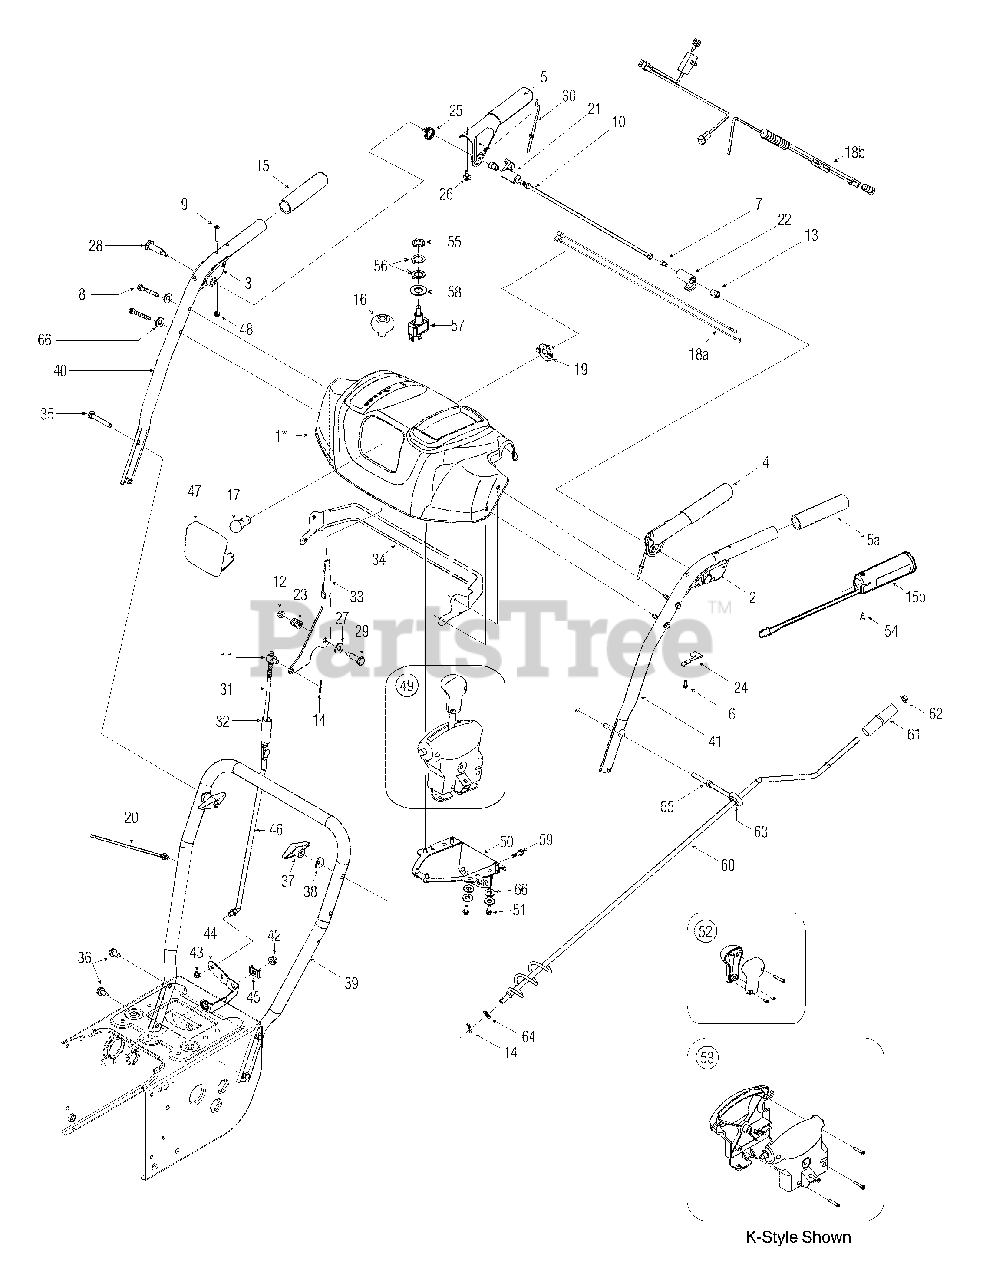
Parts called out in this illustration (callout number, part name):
1	Panel Ass'y, Handle, Black, H-Style
2	Handle Assembly, Clutch Lock, LH
3	Handle Assembly, Clutch Lock, RH
4	Handle Assembly, Engagement, LH
5	Handle Assembly, Engagement, RH
6	Screw, #8-16 x.50
7	Screw, 1/4-20 x.375
8	Screw, Self-tapping, 1/4-20 x 1.750
9	Screw, Machine, #10-24 x 1.375
10	Rod, Pivot
11	Ferrule, 5/16-18 x.312
12	Nut, Flange Lock, Nylon, 1/4-20
13	Nut, Shoulder, Hex, 1/4-20,
14	Pin, Cotter,.072 Dia. x 1.13
15A	Grip, 1.0 ID x 5.0
15B	Heated Grip
16	Knob, Shift
17	Lamp
18A	Harness, w/o Heated Grips
18B	Harness, Heated Grips
19	Socket, Lamp
20	Tie, Cable, 19 x 8.39", Tree Mount
21	Plate, Lock
22	Cam, Clutch Lock
23	Spring, Compression,.39 x.60 x.88
24	Spring, Clutch, Lock
25	Spring, Torsion, 0.8156 ID x.3038
26	Bumper, Rubber,.62 OD x.22
27	Washer, Flat,.385 x.870 x.092
28	Screw, Shoulder,.437 x 1.345, 1/4-20
29	Screw, Shoulder,.374 Dia. x 1.05
30	Z-Fitting, Cable
31	Rod, Shift,.312 x 9.0 Upper
32	Connector Sleeve, Shift Rod
36	Screw, 5/16-12, 0.750
37	Wing Knob, 5/16-18
38	Washer, Saddle, 320 x.93 x.060
42	Nut, Flange Lock, Nylon, 5/16-18
43	Nut, Speed,.3125 Dia.
44	Spring Lever, Shift
45	Shift Bracket Spacer
46	Shift Rod, Lower
47	Lens
48	Nut, Hex Lock, Nylon, #10-24, Gr2
49	Chute Control Assembly, 2-Way
51	Screw, 1/4-15 x.50
52	Kit. 2-Way Knob
53	Kit, Chute Control Housing
54	Screw, #10-16 x.625
55	Jam Nut, 15/32-32
56	Toggle Switch Lock Ring
57	2 Pos., Single Throw Toggle Switch
58	Flat Washer,.474 x.879 x.064
59	Shoulder Screw,.25 x.50
61	Chute Directional Control Knob
62	Push Cap
63	Rubber Grommet
64	Flat Washer,.375 x.738 x.063
65	Eye Bolt
66	Washer, Flat,.25 x.630 x.0515
